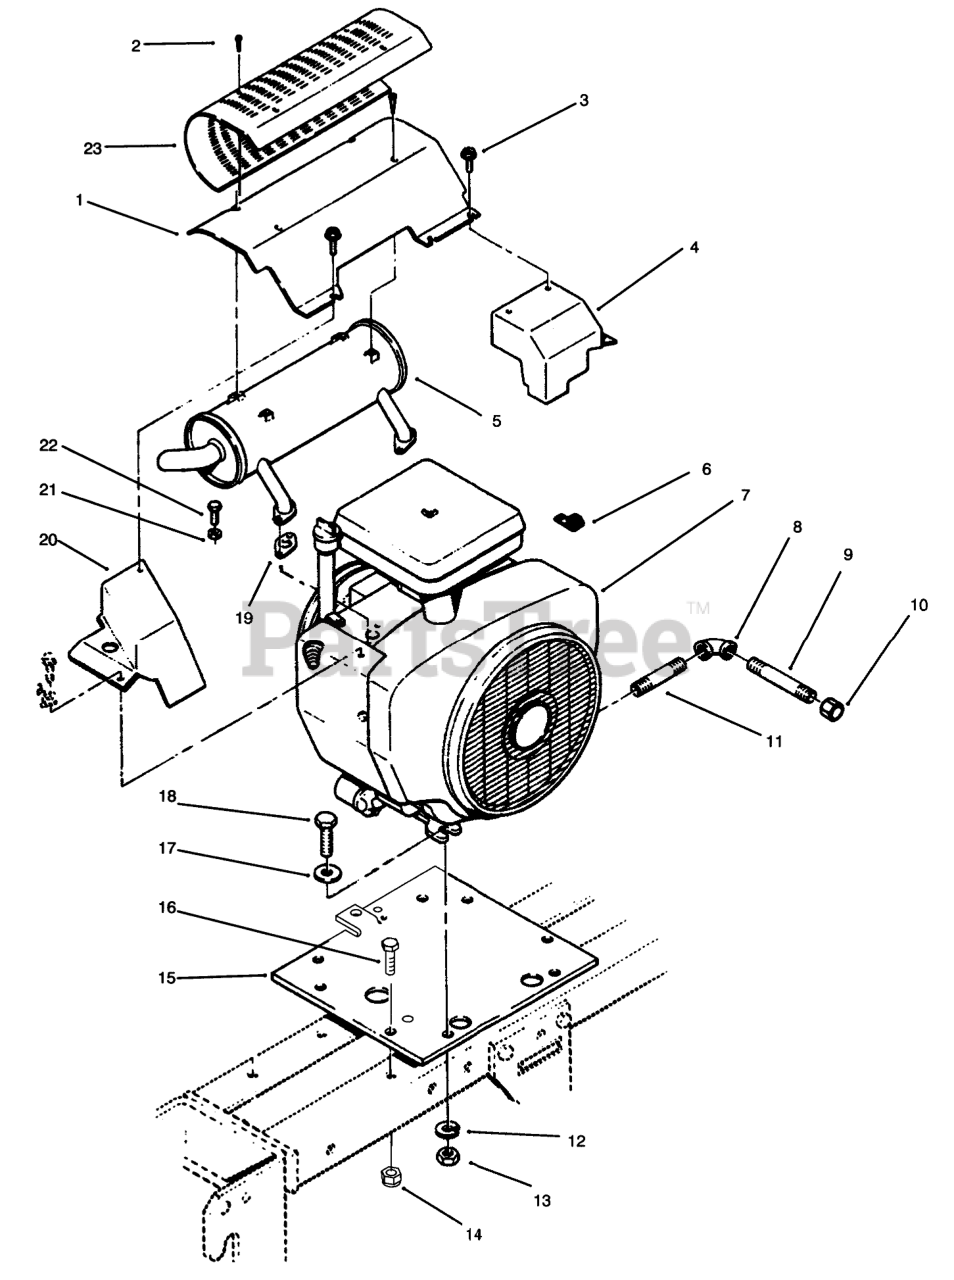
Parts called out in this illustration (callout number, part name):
1	Air Deflector
2	SCW 10-24 STAINLESS
3	SCREW
4	RH Exhaust Cover
5	MUFFLER-EXHAUST
6	CLIP
7	Engine-20HP
8	ELBOW 3/8 90 DEG
9	PIPE-NIPPLE 3/8 X 4"
10	CAP-PIPE
11	Pipe
12	WASHER-LOCK
13	NUT-HEX
14	NUT-LOCK, NI
15	PLATE-ENGINE B
16	SCREW-HH
17	WASHER-FLAT
18	SCREW-HH
19	GASKET
20	LH Exhaust Cover
21	WASHER-LOCK
22	SCREW-HH
23	SHIELD
